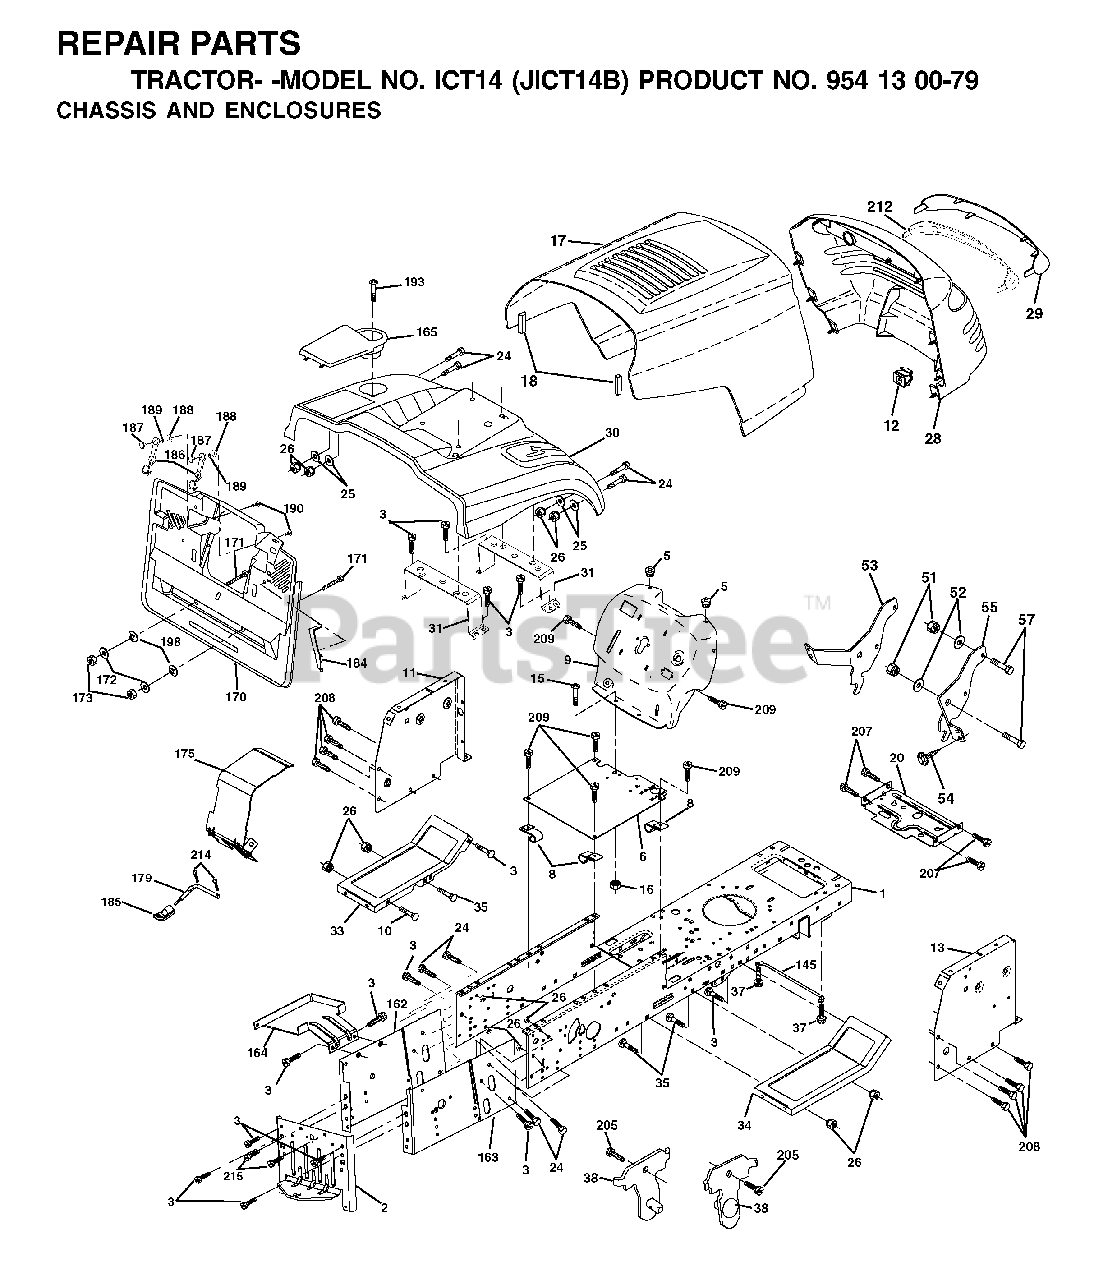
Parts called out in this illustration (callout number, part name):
1	CHASSIS
3	SCREW 3/8-16X3/4
5	BUMPER.RUBBER.HOOD
6	SADDLE FLAT
8	CLIP,INSULATOR
10	BOLT D
11	PANEL.DASH.LH.LTX
13	PANEL ASM, DASH RH
16	NUT
18	BUMPER HOOD T
20	PLATE MTG.BATTERY/FUEL TANK
25	WASHER
26	NUT
31	BRACKET SUPPORT FENDER
51	LOCKNUT
57	BOLT
145	ROD PIVOT CHASSIS/HOOD
164	SUPPORT
171	BOLT
172	WASHER
186	LATCH ASSY
187	WELDNUT
189	LOCKWASHER
193	SCREW, TRUSS 1/4-20 X 3/4"
207	SCREW
208	SCREW 3/8-16X1/2
209	SCREW, 3/8-16X3/4
214	RETAINER M
215	SCREW 5/16-18X1/2"
